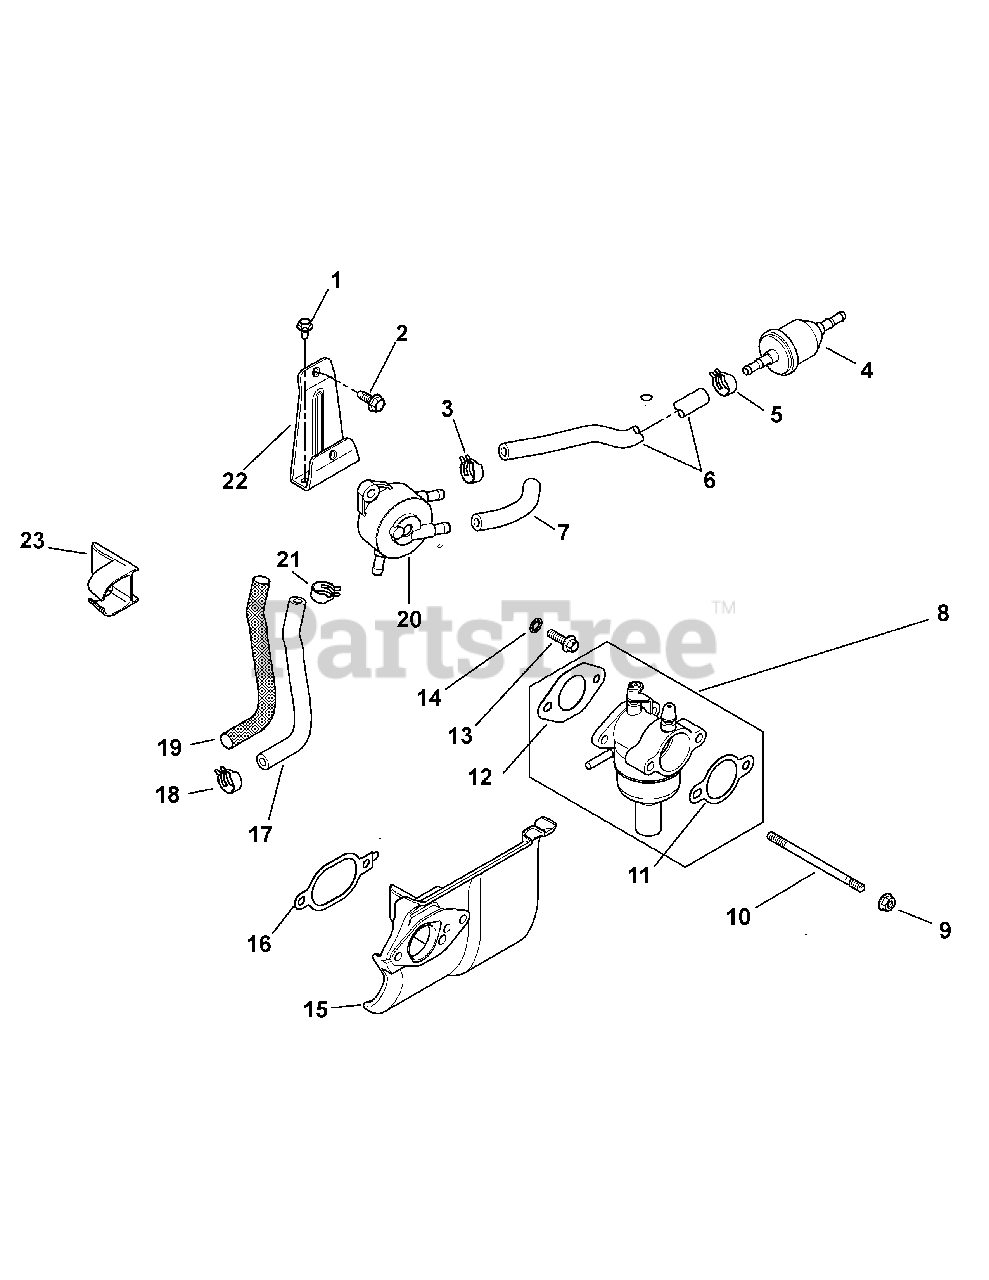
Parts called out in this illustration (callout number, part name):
1	Screw, Flg Thd Frm M5X.8X10
2	Screw, Flg Thd Frm M6X1.0X16
3	Clamp, Hose 1/2"
5	Clamp, Hose 1/2"
6	Line, Fuel (24"-Cut To Length)
7	Line, Fuel (24"-Cut To Length)
8	Carb Kit
9	Nut, Flg M6X1.0
10	Stud, M6X1.0X100
11	Gasket, Air Cleaner Base
12	Gasket, Carburetor
13	Screw, Flg M6X1.0X20
14	Washer, Int Tooth Lock 1/4"
17	Line, Fuel (24"-Cut To Length)
18	Clamp, Hose 1/2"
19	Sleeve, Fuel Line
21	Clamp, Hose 1/2"
22	Bracket, Fuel Pump Mounting
23	Insert, Intake Port
